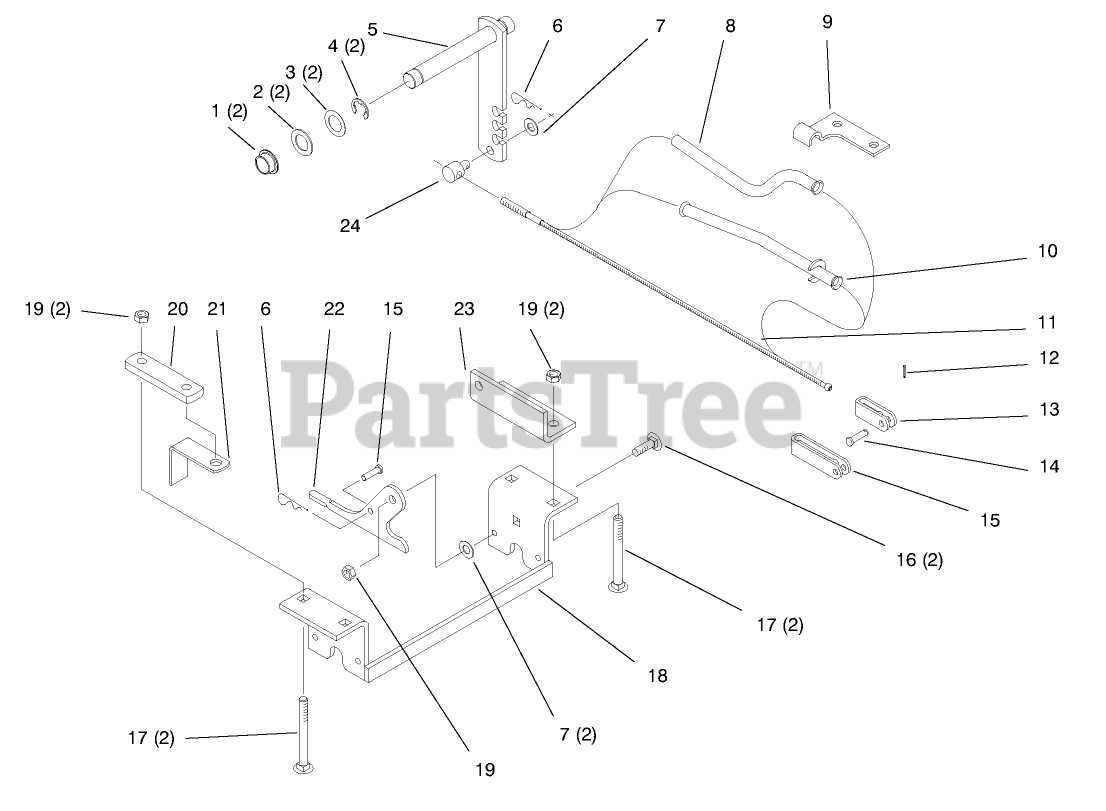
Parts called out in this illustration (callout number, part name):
1	BUSHING-BRONZE
2	WASHER
3	WASHER-SHIM
4	E-RING
6	PIN-HAIR
7	WASHER-FLAT
11	CABLE
12	PIN-COTTER
13	CLEVIS-SHORT
14	PIN-CLEVIS
15	CLEVIS-LONG
16	BOLT-CARR
17	SCREW-CARR
20	BRACKET-REAR LINK MOUNTING
21	SPACER-BRACKET
22	PLATE-LATCHING
24	TRUNNION-CLUTCH ROD
